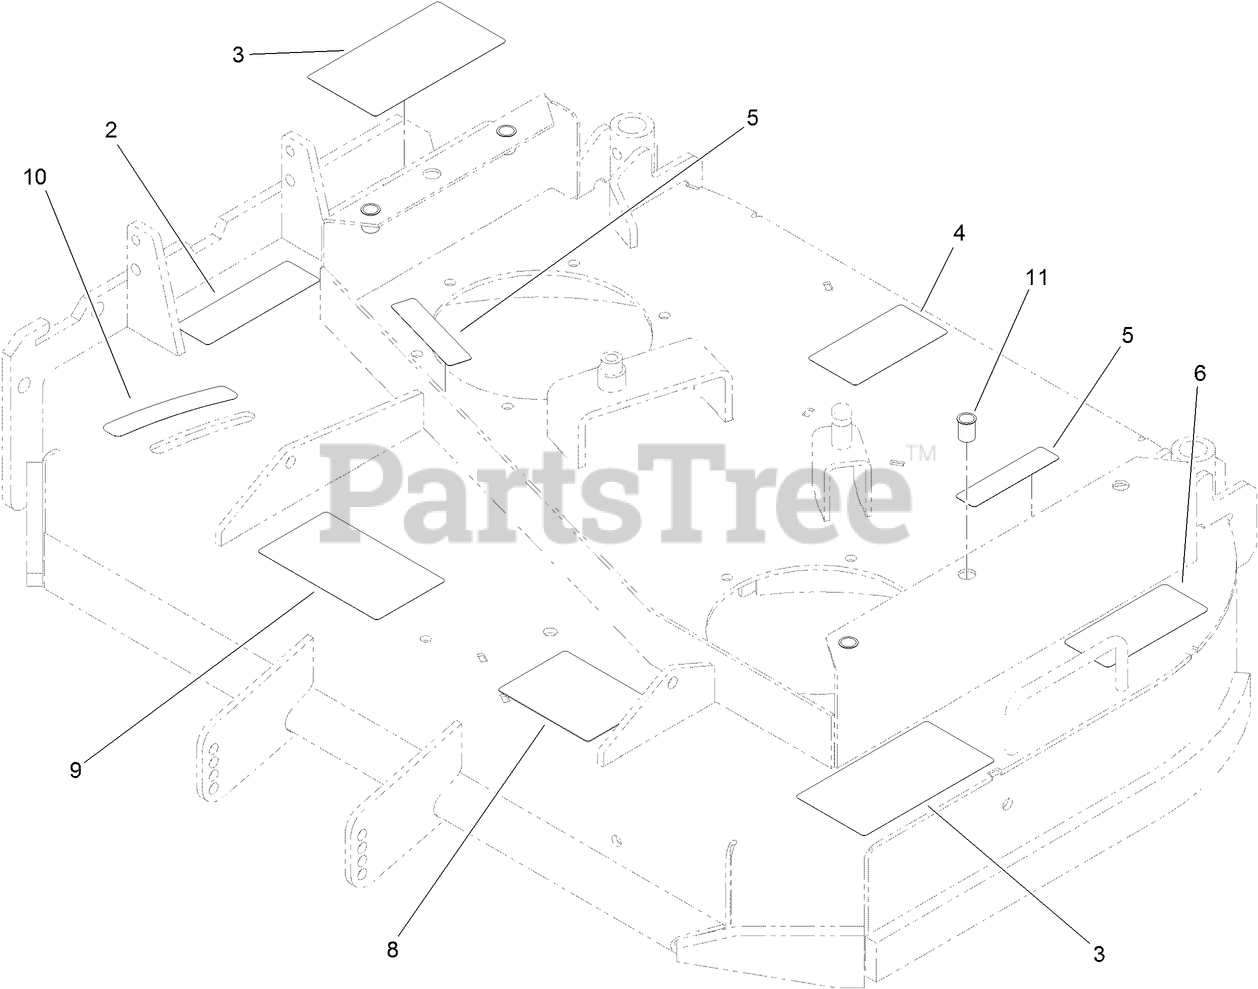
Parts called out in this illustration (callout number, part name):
2	DECAL-WARNING, DEFLECTOR
3	DECAL-DANGER
5	DECAL-WARNING
6	DECAL-TORQUE, BLADE BOLT
8	DECAL-ANTI SCALP
9	DECAL-ADJUSTMENT, BAFFLE
10	DECAL-SETTING, BAFFLE
11	INSERT-NUT
